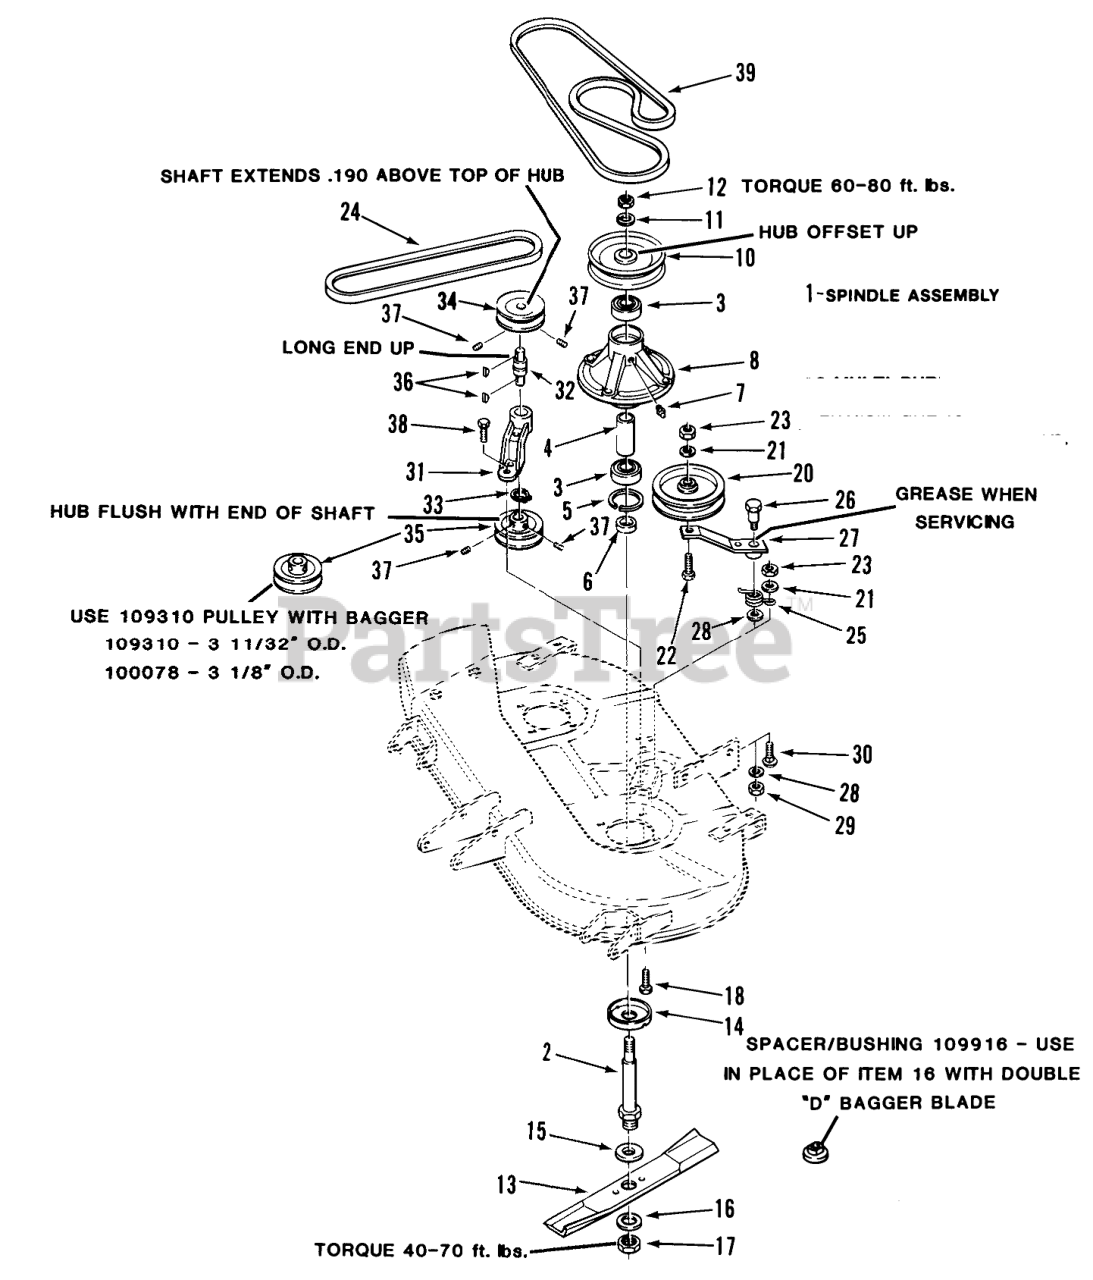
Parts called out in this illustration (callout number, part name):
1	Spindle Assembly, Metric Bearings (includes parts 2 to 8, 14)
2	SHAFT SPINDLE
3	BEARING-BALL
5	Ring-Snap
6	SPACER-BLADE
7	Fitting-Grease
8	HOUSING SPINDLE
10	PULLEY BLADE
11	Lockwasher
12	Nut
13	ASSY BLADE KIT
14	CUP-SPINDLE
15	Washer
16	SpeciaI Washer
17	Nut
18	Bolt
20	Idler Pulley
21	Washer
22	BOLT
23	Nut
24	V-BELT
25	SPRING-TORSION
26	BOLT-SHOULDER
27	Idler Arm
28	WASHER
29	NUT-JAM(7/16-14)
30	Bolt
31	HOUSING DRIVE BRG R
32	BEARING-INT SHAFT
33	Snap Ring
34	PULLEY
35	PULLEY LOWER
36	KEY-WOODRUFF
37	Set Screw
38	Bolt
39	V-BELT
